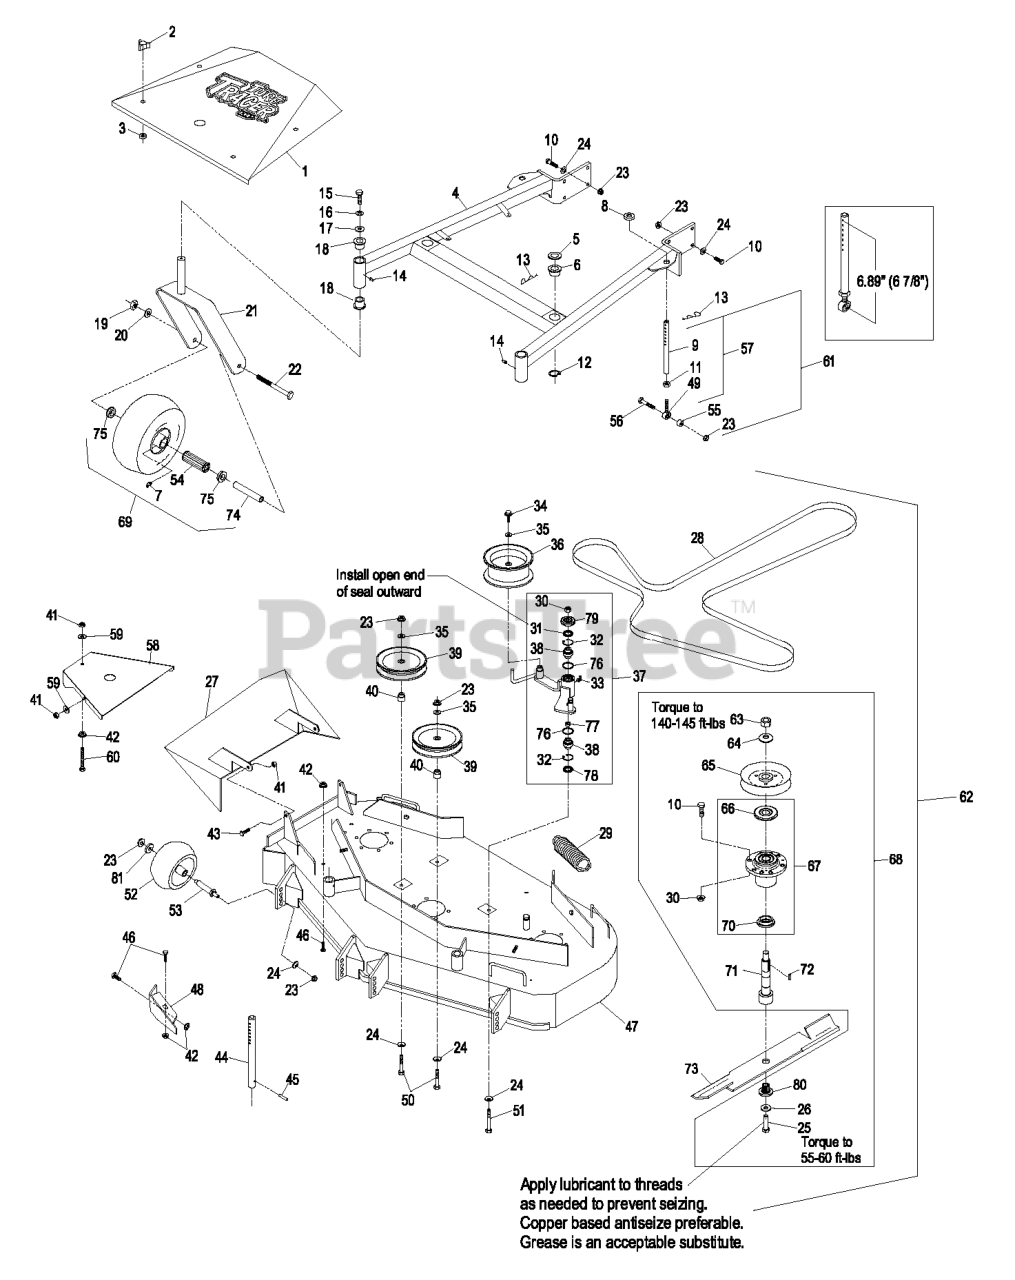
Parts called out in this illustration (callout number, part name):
2	KNOB-3 PRONG
4	DECK SUPPORT W/BSHGS 48"
5	SPACER-DECK SUPPORT
6	BUSHING-DECK
7	FITTING-GREASE
9	LINK,SUPPORT
10	SCREW-HH
11	NUT-HEX
12	RING-RETAINING
13	PIN,HAIR COTTER
14	FITTING-GREASE
15	SCREW-HH
16	WASHER-LOCK
18	BEARING-FLANGED
19	NUT-HH
20	WASHER-LOCK
22	SCREW-HH
23	NUT-HHF, WHIZ
24	WASHER-BELLEVILLE
25	SCREW-HH
26	WASHER-SPRING
27	WLD,DISCHARGE CHUTE 36/48
28	BELT - V, B
30	NUT-LOCK, NI
31	SEAL-LIP, SINGLE
32	RING-SNAP
33	FITTING-GREASE, 90 DEG
34	SCREW-HHF
35	WASHER-FLAT
37	KIT, DECK IDLER TTHP48&52
38	BEARING-SPHERICAL
39	PULLEY-IDLER
40	BUSHING-IDLER
41	NUT-LOCK, NI
43	SCREW-HH
44	ROD,DECK SUPPORT
46	SCREW-HH
47	ASM,DECK W/DECALS TTHP/MH
49	BALLJOINT
50	SCREW-HH
51	SCREW-HH
52	ROLLER-SCALP, ANTI
54	BEARING
56	SCREW-HH
58	SHIELD,BELT
59	WASHER-FLAT
60	BOLT,TAP HH
61	KIT,SUPPORT LINK W/PIN
62	Asm, Deck Complete
65	SHEAVE,W/HUB 5.72
66	GUARD-BEARING, TOP
67	KIT, CUTTER HOUSING
68	ASM, CUTTER HSG
69	KIT, SP CASTER WHEEL REPL
70	SPACER-GUARD, BOTTOM
71	KIT, SPLINED SPINDLE 103-
72	KEY-RECTANGLE
75	BUSHING
78	SEAL-LIP, DOUBLE
79	GUARD-TOP
80	BUSHING,SPLINED
